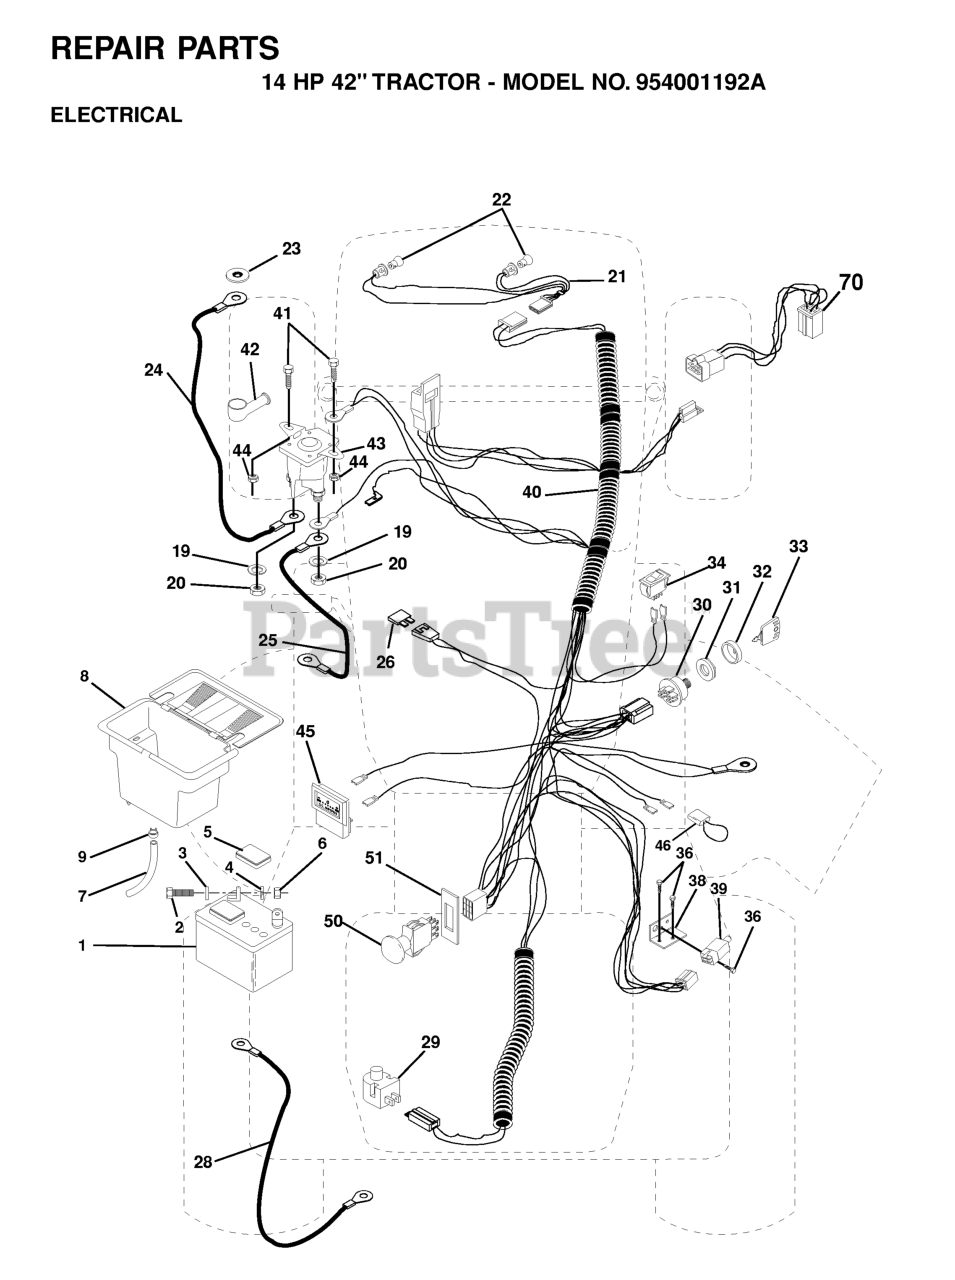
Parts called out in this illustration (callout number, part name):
1	BATTERY
2	BOLT.HEX.1/4.X.3/4.DICHROMATE
4	LOCKWASHER
5	CAP BATTERY NLA
6	NUT
7	TUBE BATTERY DRAIN
8	CASE BATTERY
9	HOSE CLAMP T
19	LOCKWASHER
20	NUT
21	HARNESS LIGHT SOCKET
23	Washer, Lock, Internal Tooth 1/4
24	CABLE-BATTERY YTV
25	STEERING CABLE GT
28	CABLE T
29	RP.SWITCH.PLUNGER.NC.GRAY
30	IGNITION SWITCH
31	NUT, IGNITION
32	COVER SWITCH KEY
33	KEY MLD GEN DELTA
35	BRACKET LT
39	SWITCH INTERLOCKT
40	HARNESS, IGNITION
41	BOLT
42	TERMINAL COVER
43	SOLENOID
44	Nut, Keps Blk Hex 1/4-20 UNC
46	WIRE PROTECTION LOOP
50	SWITCH-PTO
51	FRAME RETAINING RING
70	HARNESS, ENGINE NLA
